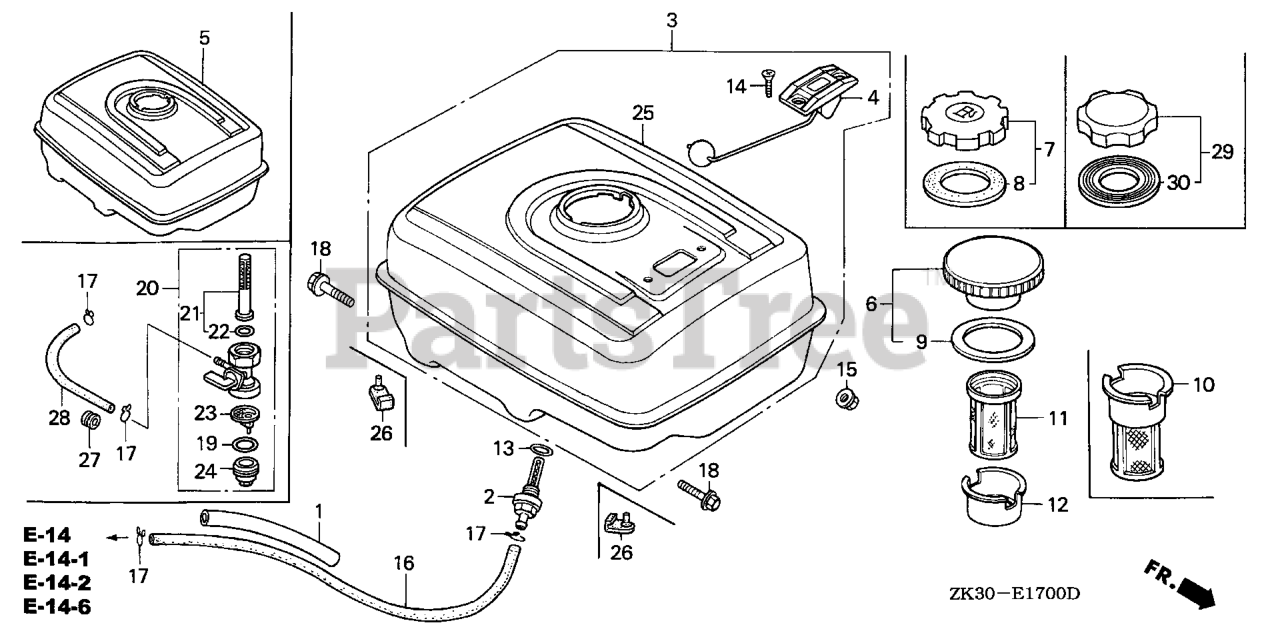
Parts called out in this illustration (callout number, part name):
1	RUBBER, SUPPORTER (107MM)
2	JOINT, FUEL TANK
5	TANK, FUEL *NH1* (BLACK)
7	CAP, FUEL FILLER (BLACK) Use up to Engine SN 2115700.
7	CAP, FUEL FILLER (CHROME PLATED)
7	CAP COMP
8	GASKET, FUEL FILLER CAP (39X58X3) (NOT AVAILABLE)
8	GASKET, FUEL FILLER CAP Use from Engine SN 1543258.
8	GASKET, FUEL FILLER CAP (39X58X3)
10	FILTER, FUEL
13	O-RING (14MM) (ARAI) Use up to Engine SN 2949254.
15	NUT, FLANGE (8MM)
16	BULK HOSE, FUEL (4.5X3000) (Honda Code 5137104). (4.5X140)
17	CLIP, TUBE (B8)
18	BOLT, FLANGE (8X25)
